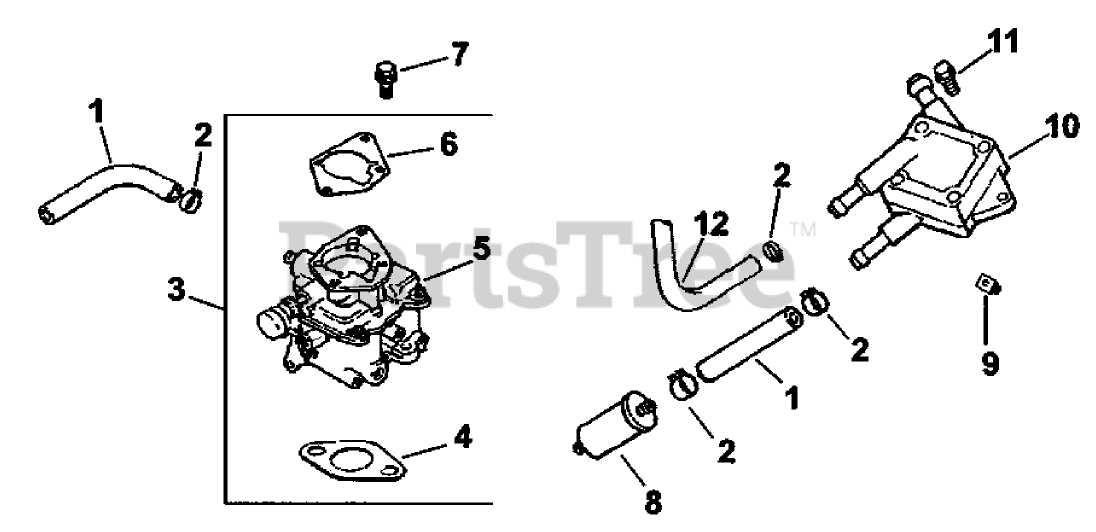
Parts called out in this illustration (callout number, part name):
1	Line-Fuel (9.5)
2	CLAMP-HOSE, SPRING (1/2)
3	Kit-Carburetor w/ Gasket (Incl. Ref. # 4-6)
4	GASKET-BASE, AIR CLEANER
5	Carburetor Asm
6	Gasket-Carburetor
7	SCREW-FLANGE (M6X1.0X30)
8	Filter-Fuel
9	Nut-Plastic
10	PUMP-FUEL
11	SCREW-TAP (M6X1.7X18)
12	Line-Fuel, Flexible (15.5)
